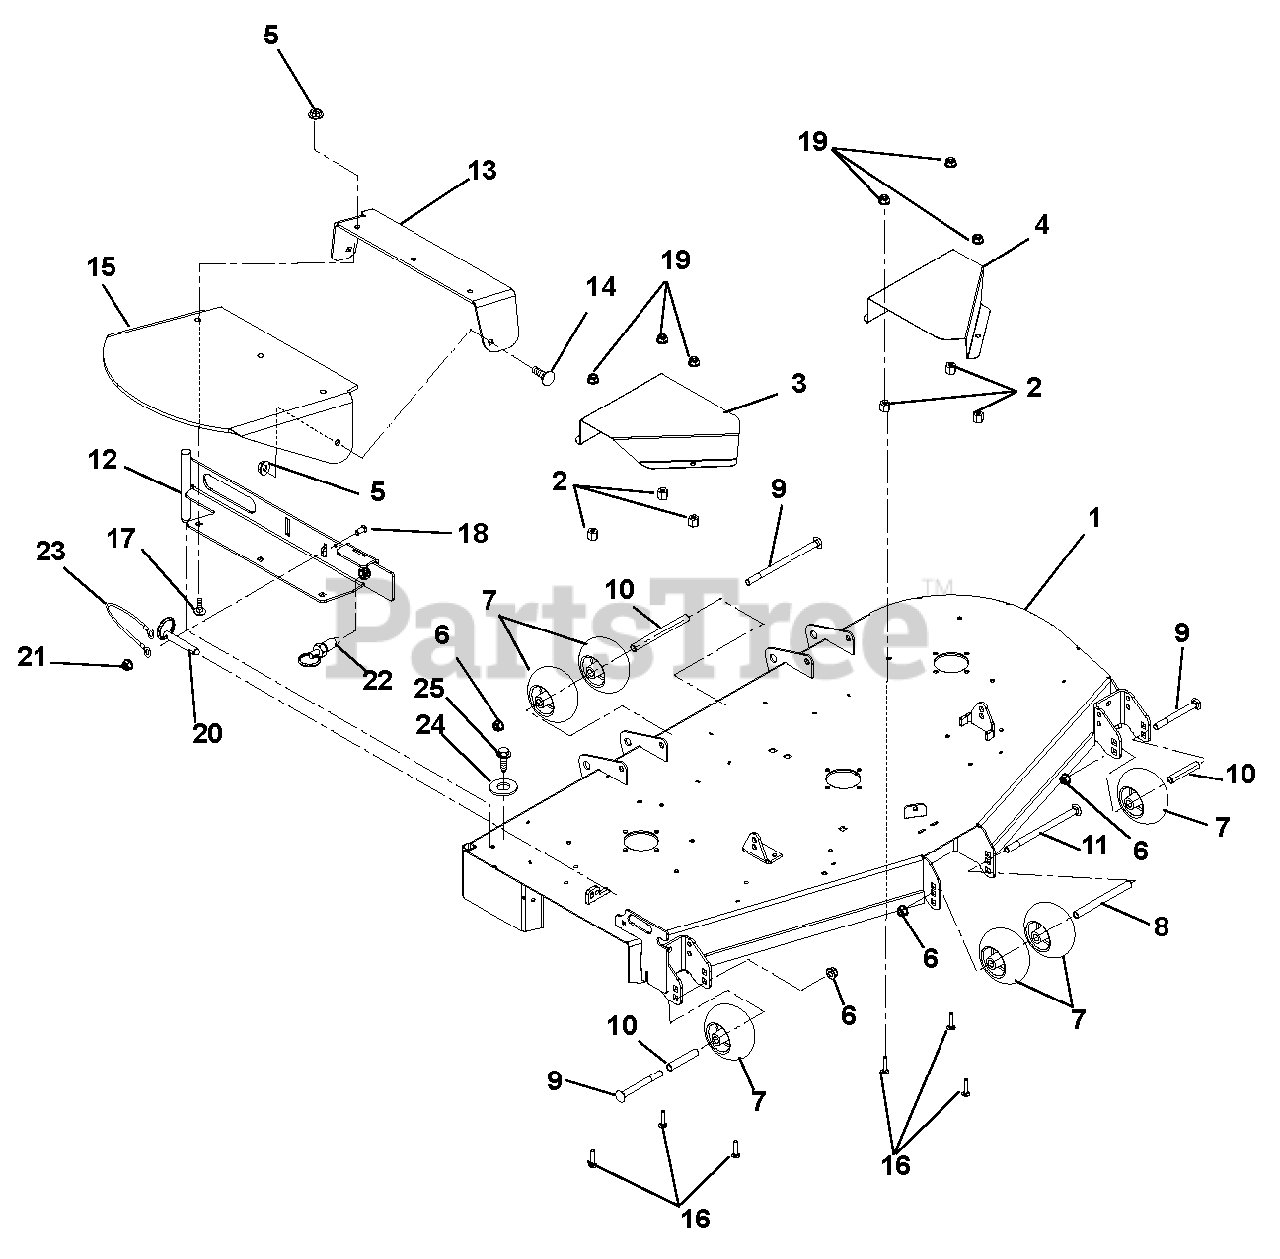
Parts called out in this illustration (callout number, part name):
1	Kit, Deck, 60" with Safety Decals (991084, 101)
1	Kit, Deck, 52" with Safety Decals (991083, 100)
1	Kit, Deck, 48" with Safety Decals (991082, 099)
1	Kit, Deck, 44" with Safety Decals (991090, 098)
2	Nut, Heavy Hex .38-16
3	Guard, 60" Spindle Sheave Right Hand (991084, 101)
3	Guard, 48"-52" Spindle Sheave Guard Right Hand (991082, 083, 090, 098, 099, 100)
4	Guard, 60" Spindle Sheave Left Hand (991084, 101)
4	Guard, 52" Spindle Sheave Left Hand (991082, 083, 090, 098, 099, 100)
5	Nut .38-16 Nyloc Flange
6	Nut .50-13 Nyloc Flange
7	Anti-Scalp Wheel (991082, 099)
7	Anti-Scalp Wheel (991083, 084, 090, 098, 100, 101)
8	Spacer, Anti-Scalp Wheel (991082, 099)
8	Spacer, Anti-Scalp Wheel (991083, 084, 090, 098, 100, 101)
9	Bolt, Round Head Square Neck .50-13 x 5.00 (991082, 099)
9	Bolt, Round Head Square Neck .50-13 x 5.00 (991083, 084, 090, 098, 100, 101)
10	Spacer, .510 x .625 x 3.35 (991082, 099)
10	Spacer, .510 x .625 x 3.35 (991083, 084, 090, 098, 100, 101)
11	Bolt, Round Head Square Neck .50-13 x 8.50 (991082, 099)
11	Bolt, Round Head Square Neck .50-13 x 8.50 (991083, 084, 090, 098, 100, 101)
12	Weldment, 44" & 48" Discharge Chute Mounting (991082, 098, 099)
12	Weldment, 52" – 60" Discharge Chute Mounting (991083, 084, 100, 101)
13	Rubber Discharge Chute Support
14	Bolt, Round Head Square Neck .38-16 x 1.00 Grade 5
15	Chute, Rubber Discharge
16	Bolt, Hex .38-16 x 1.25 Grade 5
17	Bolt, Round Head Square Neck .38-16 x 1.25 Grade 5
18	Bolt, Hex .25-20 x .75 Grade 5 (991082, 090, 098, 099)
19	Nut, Flange .375-16
20	Pin, Spring Ball .375 OD x 1.50 (991082, 090, 098, 099)
21	Nut, Locking Top Flange .25-20 (991082, 090, 098, 099)
22	Pull Pin
23	Cable, 6.00 Lanyard – Nylon (991082, 090, 098, 099)
24	Bumper, Recessed 1.50 x .63 W/.31 Thru Hole
25	Screw, Tapping .31-18 x .75 Hex Washer Head
